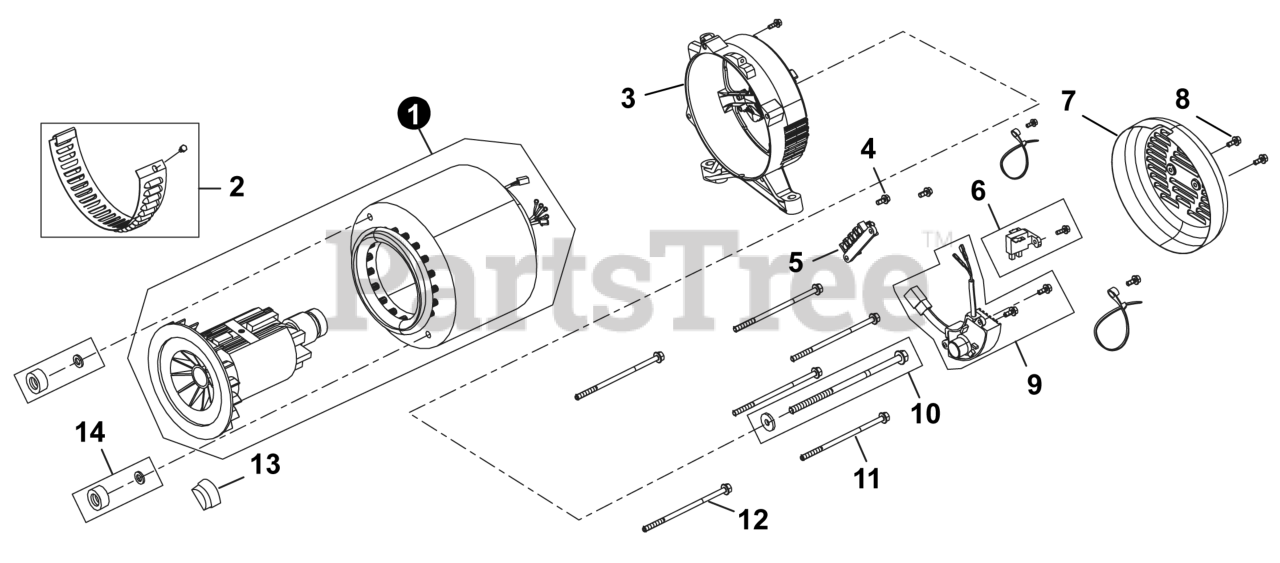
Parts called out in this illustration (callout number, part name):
1	GENERATOR ASSY.
2	SHROUD, MOTOR
3	BRACKET, MOTOR
5	BLOCK, TERMINAL
6	BRUSH, CARBON
7	COVER, MOTOR TAIL
9	REGULATOR, VOLTAGE
10	BOLT, STATOR
11	BOLT, ROTOR
12	BOLT, STATOR
13	STOPPER, MOTOR RIGHT COVER
14	NUT, STATOR
